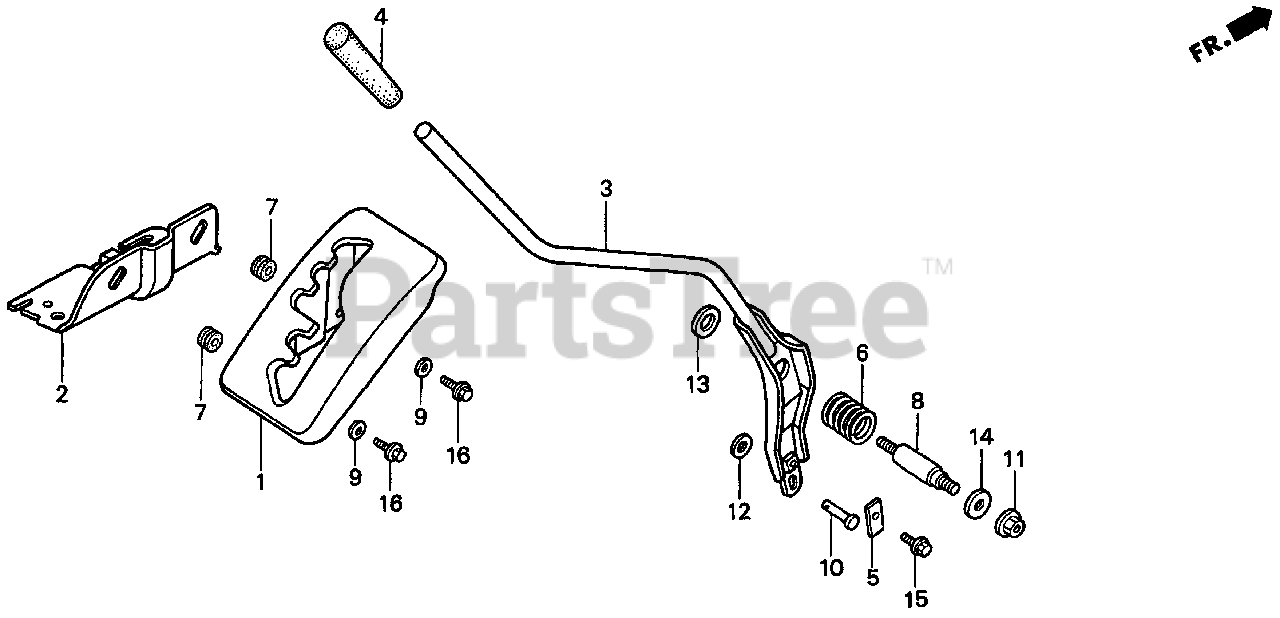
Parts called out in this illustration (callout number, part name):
1	COVER, CHANGE
2	STAY, CHANGE COVER
3	LEVER, CHANGE
4	GRIP, CHANGE LEVER
5	PLATE, CHANGE LEVER PIN
6	SPRING, CHANGE LEVER
7	GROMMET A, TUBE
8	BOLT, CHANGE LEVER
9	WASHER (6X20)
10	PIN, CLUTCH ARM
11	NUT, FLANGE (8MM)
12	WASHER, PLAIN (6MM)
13	WASHER, PLAIN (10MM)
14	WASHER, PLAIN (8MM)
15	BOLT, FLANGE (6X12)
16	BOLT, FLANGE (6X16)
